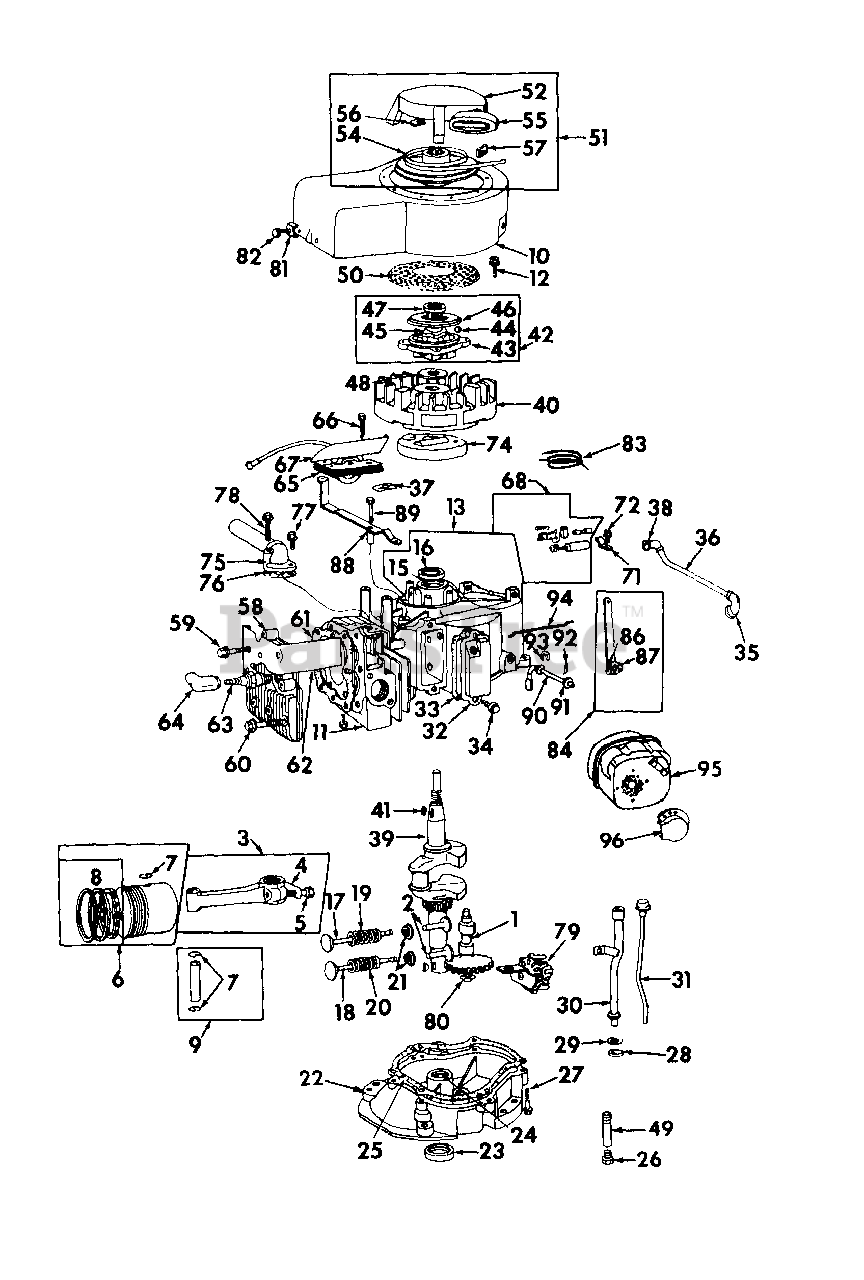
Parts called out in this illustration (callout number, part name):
2	TAPPET, VALVE
3	ROD ASSY, CONNECTING STD
4	LOCK, SCREW HEAD
5	SCREW, CONNECTING ROD
6	PISTON ASSY, STD
7	RETAINER, PISTON PEN
8	RING SET, PISTON CHROME STD
9	PIN, PISTON - STD
10	HOUSING, BLOWER
11	SHIELD, CYLINDER
12	SCREW, 8-32 X 3/8 ZND HEX-HD
13	CYLINDER ASSY, ENGINE
15	BUSHING & SEAL
16	SEAL, OIL
17	VALVE, INTAKE
18	VALVE, EXHAUST
19	SPRING, INTAKE VALVE
20	SPRING, EXHAUST VALVE
21	RETAINER, VALVE SPRING
22	BASE ASSY, CRANKCASE
23	OIL SEAL, BASE
24	BUSHING & OIL SEAL
25	GASKET, BASE-STD
26	PLUG, 1/4-18 AUTOMOTIVE HEX HD PIPE
27	SCREW, CRANKCASE BASE
28	SEAL, OIL FILLER TUBE
29	RETAINER, OIL FILLER TUBE SEAL
30	TUBE, OIL FILLER
31	GAUGE, OIL LEVEL
32	BREATHER, VALVE CHAMBER
33	GASKET, BREATHER
34	SCREW, BREATHER MTG
35	GROMMET, BREATHER
36	TUBE, BREATHER
37	CLIP, BREATHER TUBE
38	GROMMET, BREATHER TUBE
41	KEY, FLYWHEEL
42	CLUTCH ASSY, REWIND STARTER
43	HOUSING, REWIND STARTER CLUTCH
44	BALL, 5/16 CR-STL- 25 GRADE
45	RATCHET, STARTER
46	RETAINER, WASHER
47	SEAL, RATCHET
48	WASHER, SPRING
49	PIPE, OIL DRAIN
50	SCREEN, REWIND STARTER
51	STARTER ASSY, REWIND
52	HOUSING, REWIND STARTER
54	SPRING, REWIND STARTER
55	PACKAGE, REWIND STARTER HANDLE & INSERT
56	BUMPER, REWIND PULLEY
57	ANCHOR, SPRING
58	HEAD, CYLINDER
59	SCREW, CYLINDER HEAD-SHORT
60	SCREW, CYLINDER HEAD-LONG
61	GASKET, CYLINDER HEAD
62	COVER, CYLINDER HEAD
63	PLUG, RESISTOR SPARK -CHAMPION-
64	ELBOW, SPARK PLUG INSULATOR
65	ARMATURE ASSY, MAGNETO
66	SCREW, ARMATURE MOUNTING
68	KIT, BREAKER POINT & CONDENSER
71	CLAMP, CONDENSER
72	SCREW, CONDENSER CLAMP
74	COVER, BREAKER POINT
75	TUBE, INTAKE
76	GASKET, INTAKE TUBE
77	SCREW, INTAKE TUBE-SHORT
78	SCREW, INTAKE TUBE-LONG
79	GEAR, GOVERNOR
80	WASHER, GOVERNOR GEAR
81	CLAMP, CASING
82	SCREW, CLAMP MTG
83	WIRE ASSY, STOP SWITCH
84	LEVER ASSY, GOVERNOR
86	BOLT, GOVERNOR LEVER
87	NUT, NO. 10-24 ZND HEX
88	LEVER ASSY, LINKAGE
89	SCREW, SHOULDER
90	CRANK, GOVERNOR
91	WASHER, GOVERNOR CRANK
92	COTTER, GOVERNOR CRANK
93	RETAINER, GOVERNOR CRANK
94	LINK, GOVERNOR
95	MUFFLER, EXHAUST
96	DEFLECTOR
